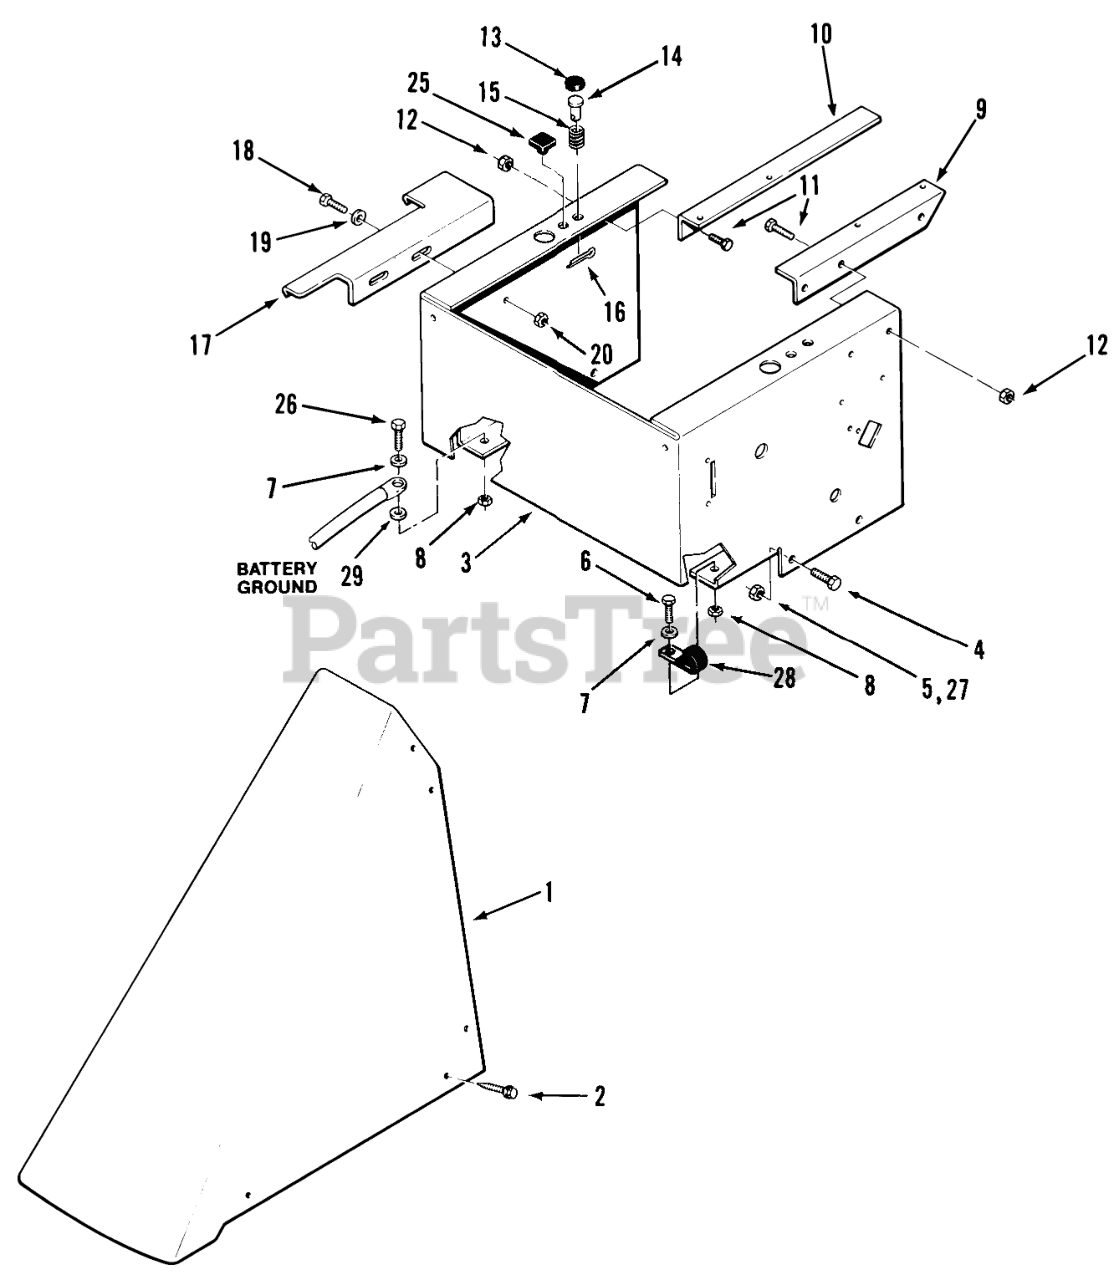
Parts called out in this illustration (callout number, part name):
1	COVER CONSOLE R
2	HEX WASHER STS
3	Seat Support
4	BOLR HWH 3/8-16X7/8
5	NUT
6	Bolt
7	WASHER 5/16 SAE
8	Nut
9	ANGLE TANK SUPP. R
10	ANGLE TANK SUPP. R
11	H H C S
12	Nut
15	SPRING
16	Cotter Pin
17	PLATE SHIFT R
18	Bolt
19	WASHER 5/16 SAE
20	Nut
25	BUMPER SJ5514 BLACK
26	Bolt
27	Nut
28	CLIP
29	Washer-Lock
